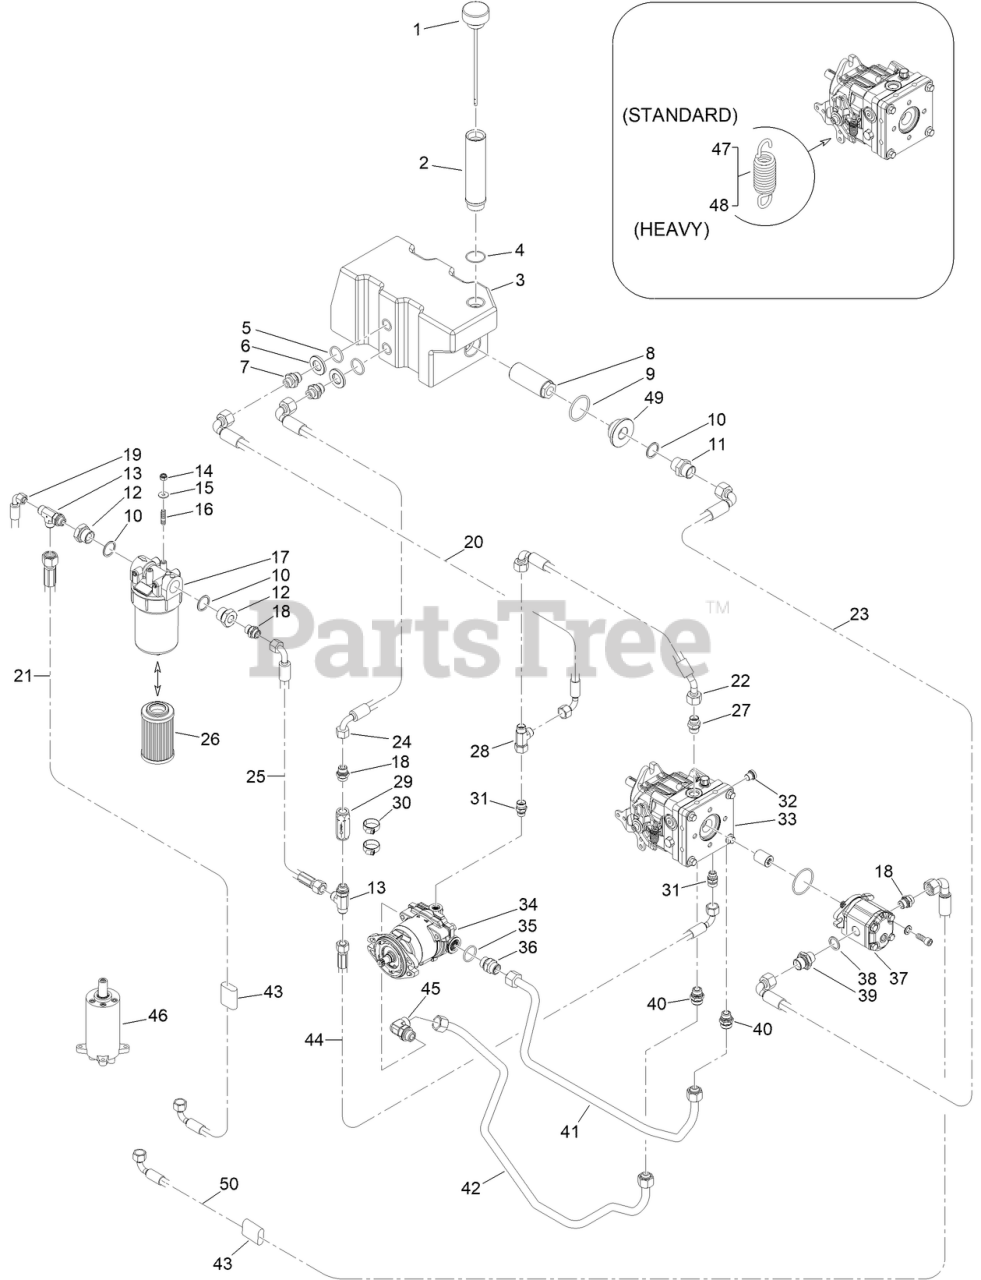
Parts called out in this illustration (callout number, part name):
1	CAP-OIL
2	FILLER-TANK, OIL
3	TANK-OIL
4	O-RING
5	O-RING
6	WASHER
7	FITTING
8	FILTER-TANK, HYDRAULIC
9	O-RING
10	WASHER
11	FITTING, NIPPLE
12	FITTING-REDUCER
13	ADAPTOR-90 DEG
15	WASHER
17	FILTER, TRANSMISSION OIL
18	FITTING-NIPPLE
26	FILTER ELEMENT, TRANSMISSION OIL FILTER
27	FITTING,NIPPLE
28	FITTING-TEE
29	CHECK-VALVE
31	FITTING-NIPPLE
32	PLUG {9/16-18 UNF L10 CE6]
33	PUMP, TRANSMISSION
34	MOTOR, TRANSMISSION
35	O-RING
36	FITTING, NIPPLE
37	GEAR PUMP
38	WASHER
39	FITTING
40	FITTING, NIPPLE
41	PIPE, FORWARD GEAR
42	PIPE, REVERSE GEAR
43	PROTECTOR-HOSE
45	FITTING
46	STEERING VALVE
47	SPRING, RTN STANDARD 51833
48	SPRING, RTN HEAVY 51605
49	SUPPORT-FILTER, OIL
